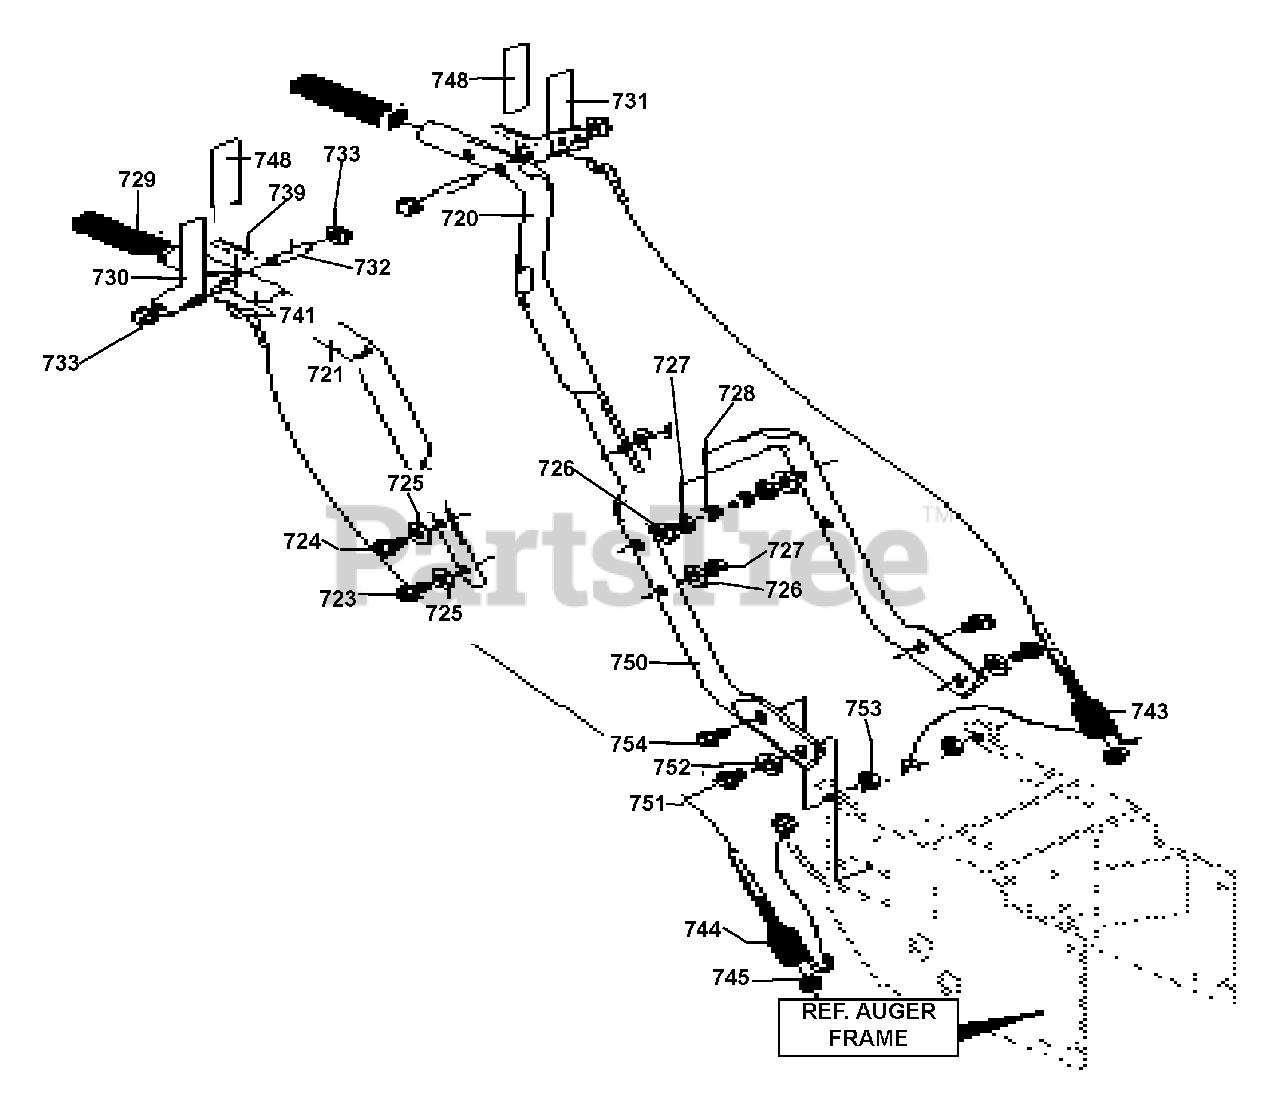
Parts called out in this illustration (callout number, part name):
720	HANDLE, UPPER LH
721	HANDLE, UPPER RH
723	SCREW, 3/8-16X2.00
724	SCREW, 3/8-16X3.00
725	WASHER, FLAT .406X.81X.065
726	WASHER, 393X.68X.10
727	NUT, 3/8-16REGHXCTRLK
728	STOP, PLASTIC
729	GRIP, HANDLE
730	ASSY, CLUTCH LEVER RH
731	ASSY, CLUTCH LEVER LH
732	PIN, PIVOT CLUTCH
733	NUT, PUSH ON NUT
739	BUMPER, FLAT
741	CABLE, CLUTCH 32.19"
743	SPRING, TENSION
744	SPRING, AUGER CLUTCH
745	NUT, 1/4-20 RGHXCTRLK
748	GRIP, CLUTCH HANDLE
750	HANDLE, LOWER
751	SCREW, 5/16-18X .75
752	WASHER, .328X.60X.09
753	NUT, 5/16-18
